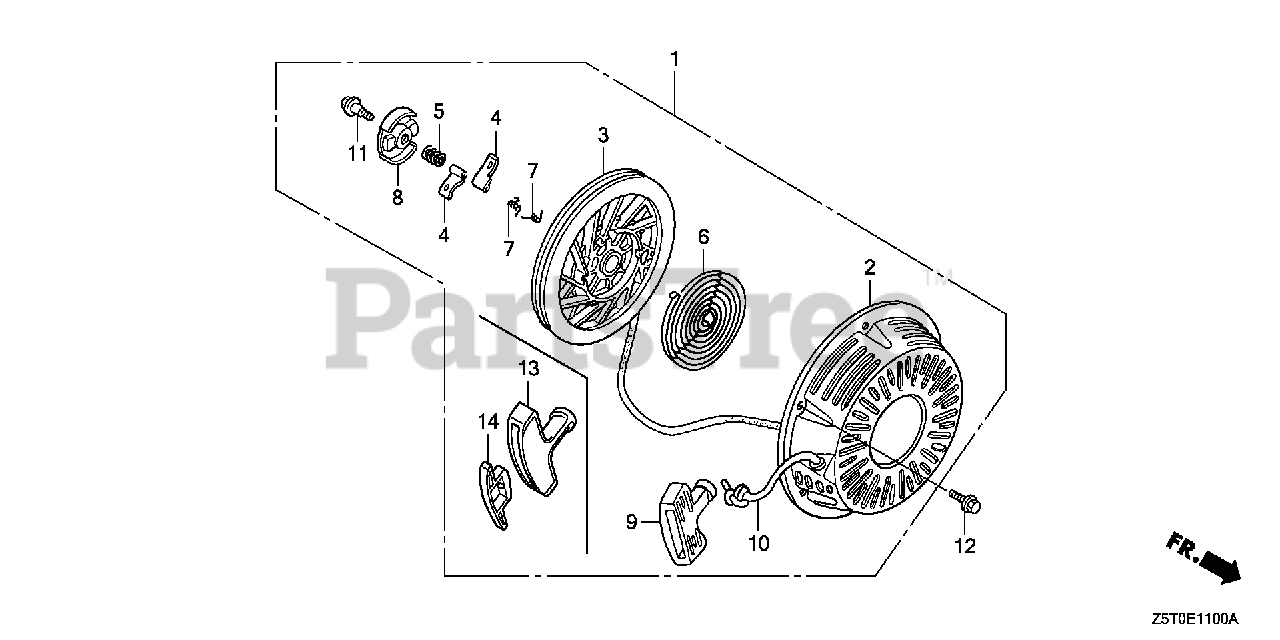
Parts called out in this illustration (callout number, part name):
1	STARTER ASSY., RECOIL *R280* (FOR U.S.A.) (POWER RED)
2	CASE, RECOIL STARTER *R280* (POWER RED)
3	PULLEY, RECOIL STARTER
4	RATCHET, STARTER
5	SPRING, FRICTION
6	SPRING, STARTER RETURN
7	SPRING, RATCHET
8	RETAINER, SPRING
10	ROPE, RECOIL STARTER
11	SCREW, CENTER
12	BOLT, FLANGE (6X10)
13	GRIP, STARTER
13	GRIP, STARTER (COO)(FOR U.S.A.)
14	GRIP, REINFORCEMENT
